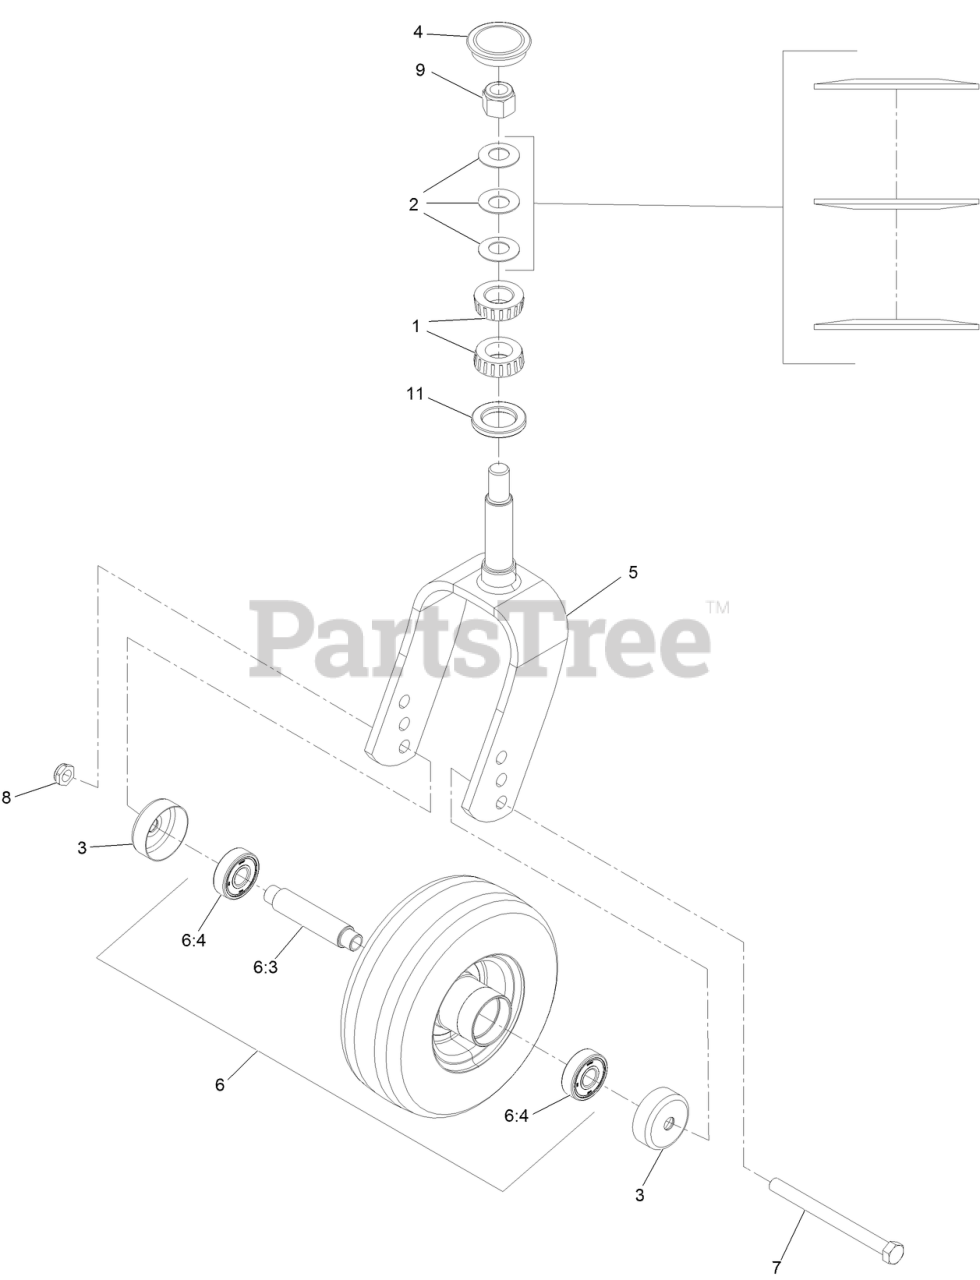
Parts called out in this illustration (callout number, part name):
1	Cone-Bearing Tapered Roller
2	WASHER-BELLVILLE
3	GUARD, SEAL
4	CAP-GREASE
5	FORK-CASTER 9"
6	WHEEL AND TIRE ASM
6:3	AXLE-CASTER
6:4	BEARING
7	SCREW-HH
8	NUT-HEX
9	NUT-LOCK, NI
11	SEAL-GREASE
